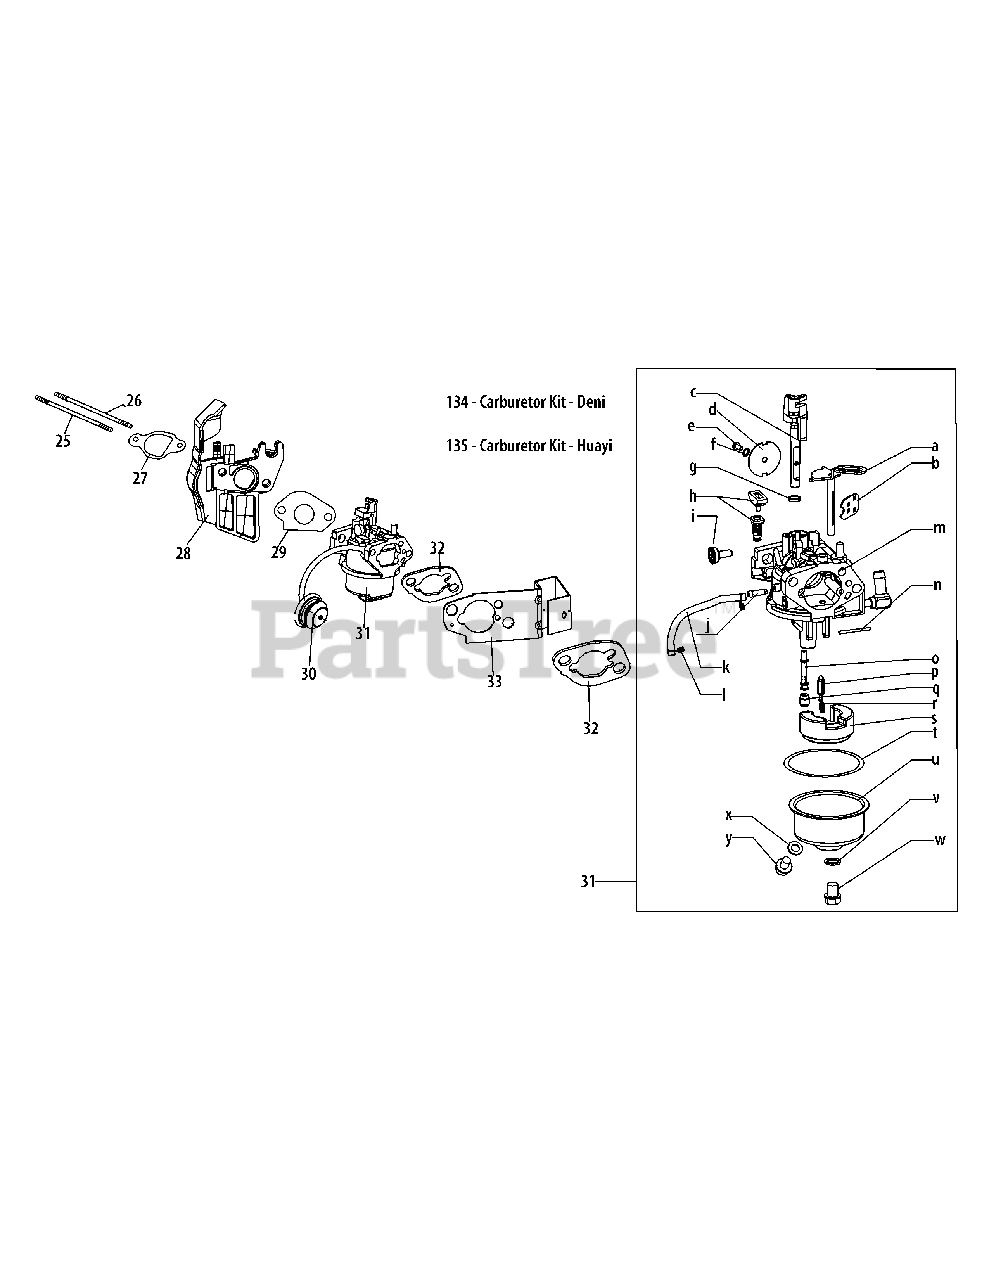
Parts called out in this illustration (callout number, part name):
25	Stud-Carb
26	Stud - M6 X 105
27	Gasket-Carb Insulator
28	Carburetor Insulat
29	Carburetor Gasket
30	Primer Bulb
31	Carburetor Assembly - Huayi
31	Carburetor Assembly - Deni
32	Carburetor Gasket
33	Bracket - Choke Control
134	Carburetor Kit - Deni
135	Carburetor Kit - Huayi
